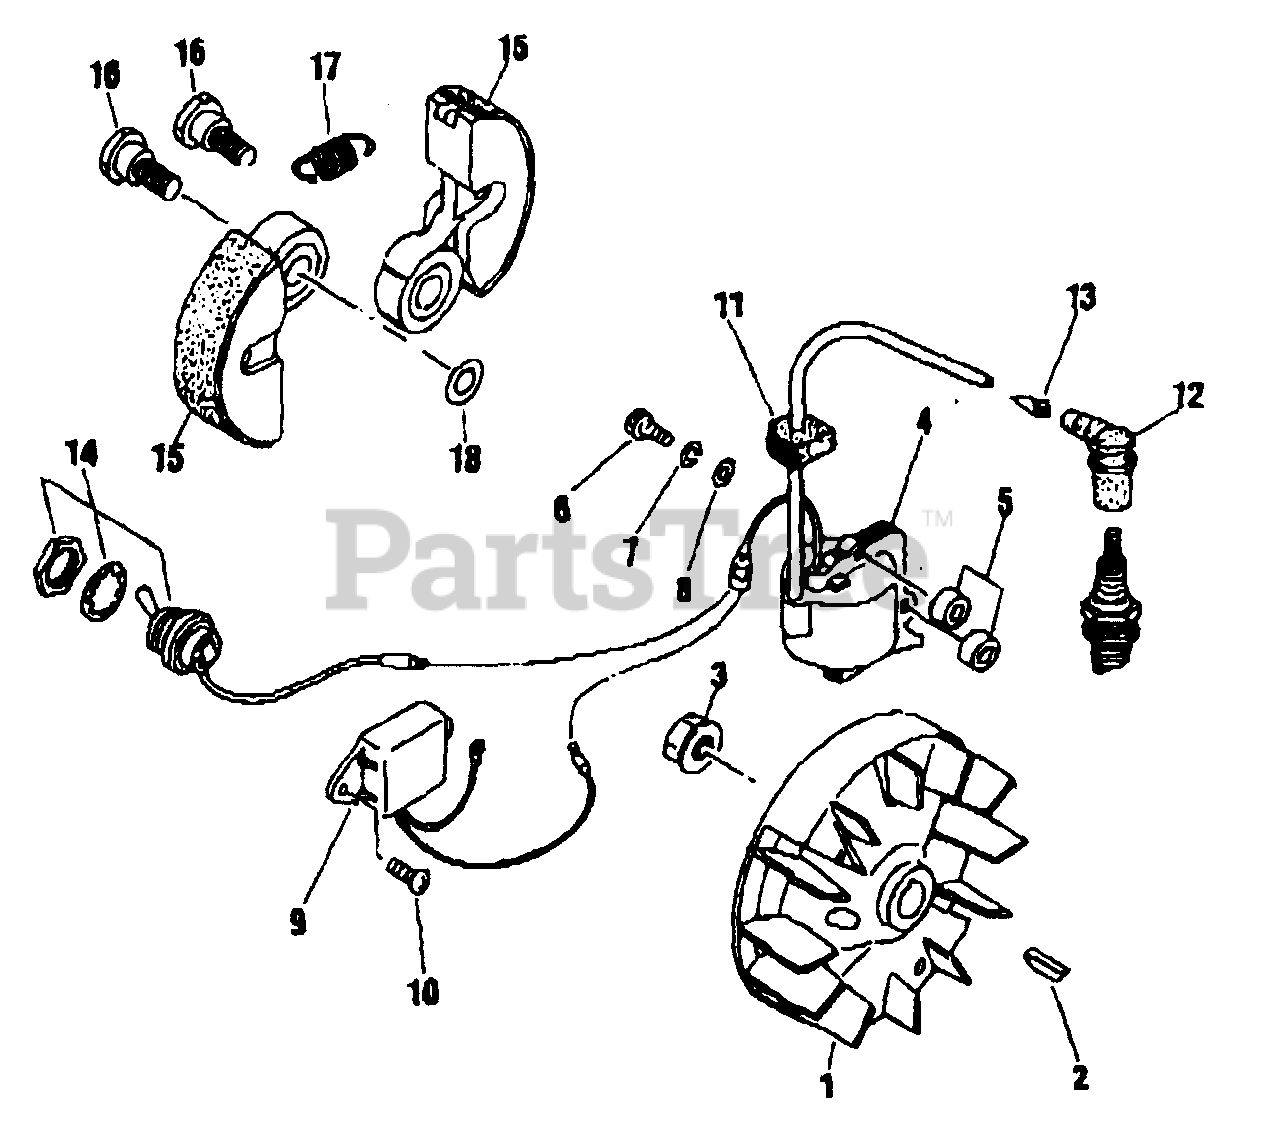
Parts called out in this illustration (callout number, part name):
1	ROTOR
2	KEY, WOODRUFF - 3×10
3	NUT M8
5	INSULATOR
6	BOLT
7	WASHER, SPRING 4 MM
8	WASHER 4.3×9.6×0.8
9	UNIT
11	GROMMET
12	CAP, SPARK PLUG
13	TERMINAL, SPARK PLUG
16	BOLT
17	SPRING, CLUTCH
18	WASHER 6 MM
